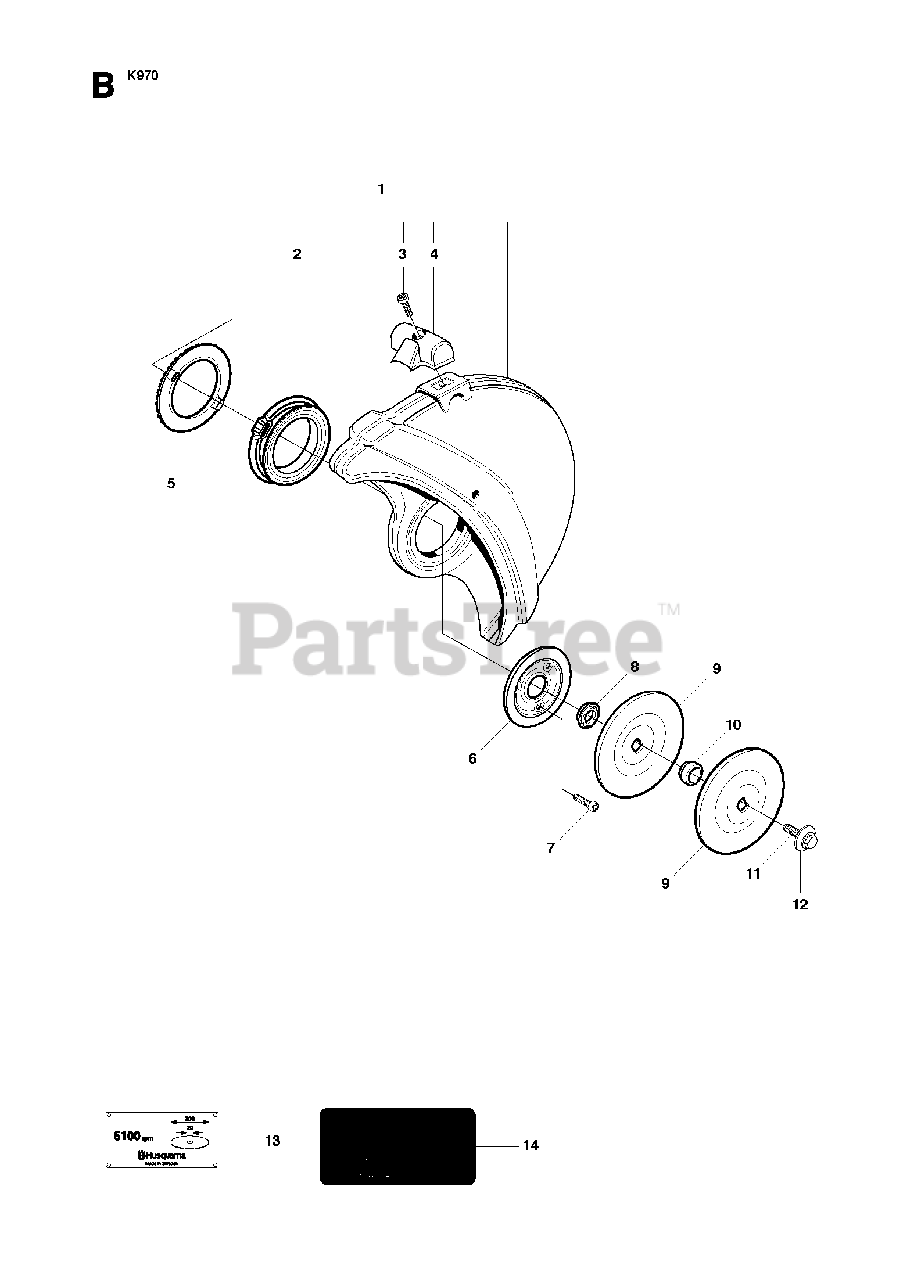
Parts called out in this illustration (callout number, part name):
1	BLADE GUARD12"
1	BLADE GUARD14"
1	BLADE GUARD16"
3	SCREW ITXSCM
7	SCREW ITXSCM
8	SUPPORT FLANGE
9	FLANGE WASHER
14	DECAL
